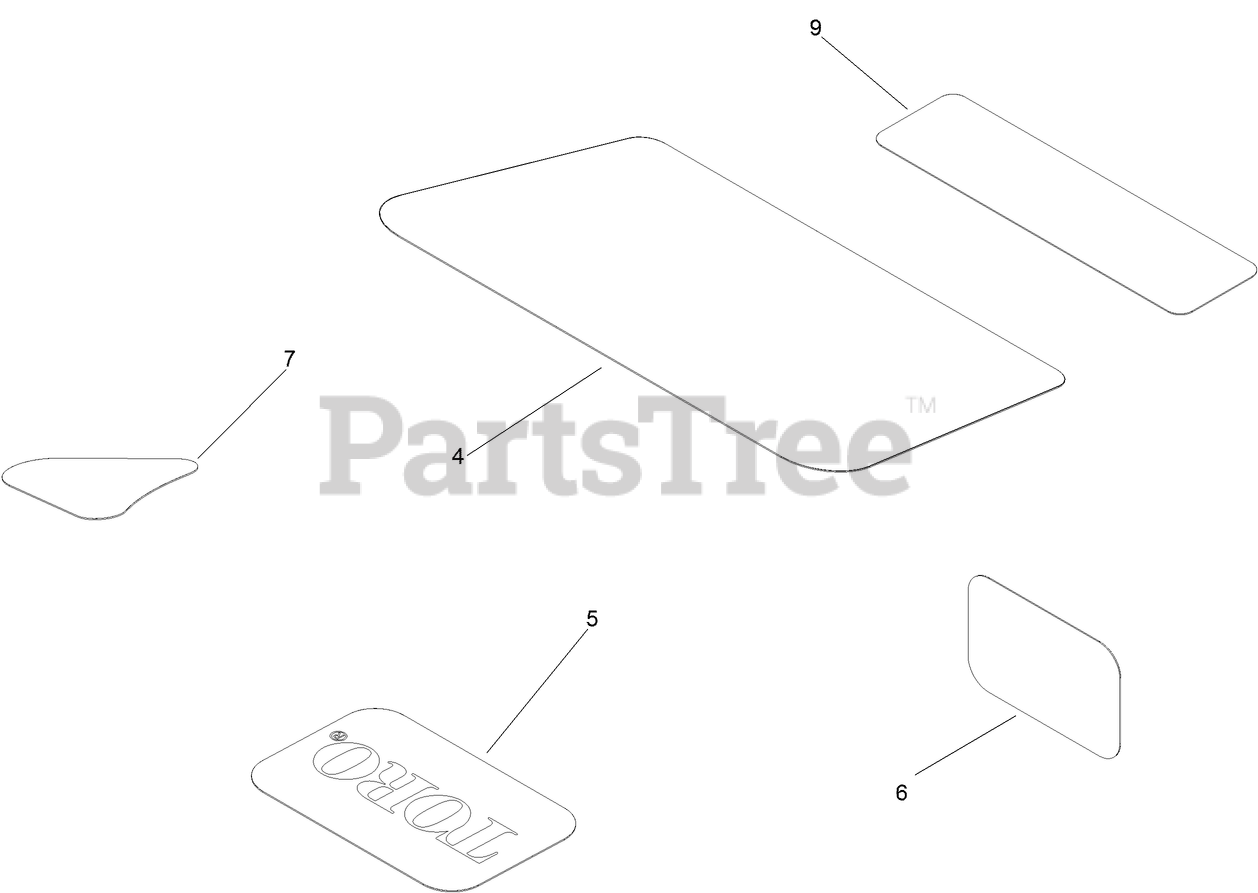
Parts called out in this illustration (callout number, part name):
4	DECAL-ENGINE
6	PLACARD-INTAKE
7	DECAL-DRAIN, OIL
9	DECAL-BUCKET
